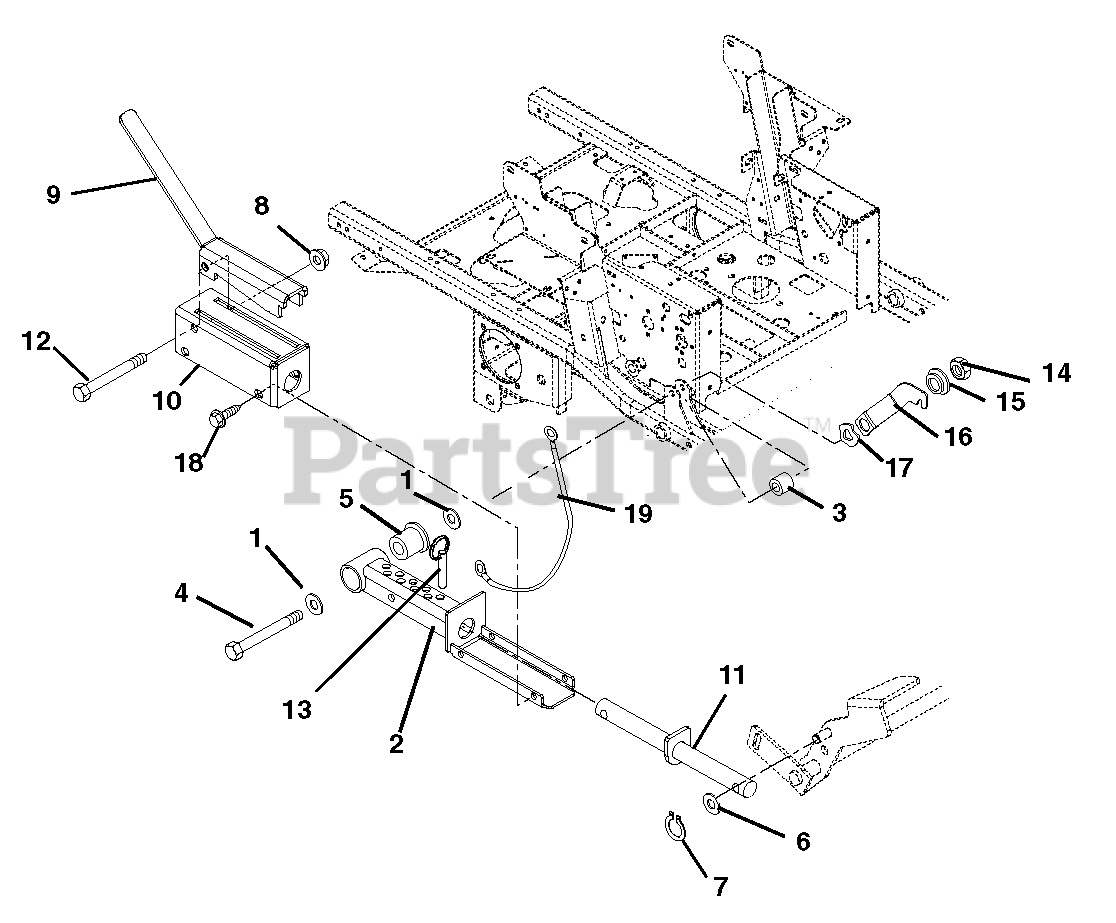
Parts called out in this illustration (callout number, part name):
1	Washer, Flat Steel .531 x 1.25 x .10
2	Weldment, Mechanical Lift Cover
3	Bushing .516 x 1.00 x 1.05
4	Bolt, Hex .50-13 x 5.00 Grade 5
5	Bearing, Pedestal
6	Washer, Flat Steel .656 x 1.310 x .095
7	Ring, Retaining External .625 x .050
8	Nut, Locking Top Flange .38-16
9	Mechanical Deck Lift Lock Lever
10	Weldment, Mechanical Lift Cover
11	Weldment, Mechanical Lift Shaft
12	Bolt, Hex .38-16 x 3.25 Grade 5
13	Pin, Spring Ball .375 O.D. x 1.50
14	Nut, Locking Top Flange .50-13
15	Bushing, Flange .515 x .75 x .275 x 1.12
16	Latch, Footboard
17	Washer, Wave .076 x 1.12 x .08
18	Screw, Tapping .38-16 x .50 Hex Washer Head
19	Cable, 12.0 Lanyard, Nylon
